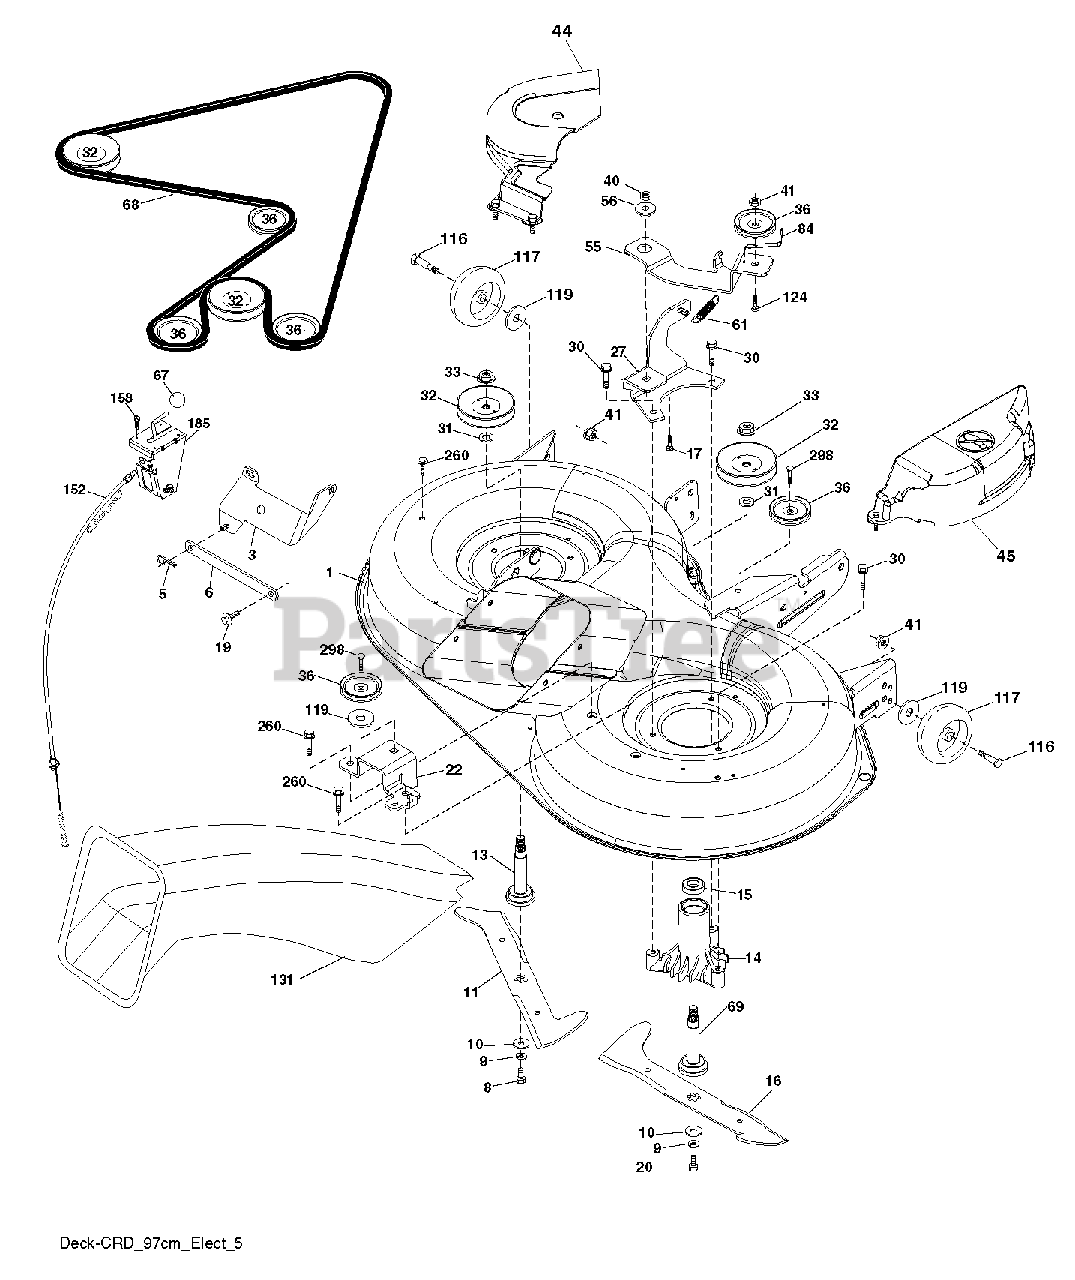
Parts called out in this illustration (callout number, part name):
1	DECK.WLDT.97.CRD.2GWB
3	BRACKET.ASM.BAR.SWAY.CHASS
5	RETAINER-SPRNG RB
6	BAR SWAY
8	Bolt, 3/8-24 X 1.25 Gr8
9	LOCKWASHER
11	BLADE.3N1.LH.CRD.97
13	SHAFT ASM VENT
16	BLADE.3N1.RH.CRD.97
17	BOLT.3/8-14X1.25
19	BOLT SHD 5/16-18
20	BOLT.3/8-24X1.25GR8. LHTHRD
22	BRACKET.SUPT.IDLER.REAR.RH
27	BRACKET.ASM.SUSP.REAR.RH.
30	SCREW, WASHER HEAD
31	WASHER.SPACER.MANDREL
32	PULLEY MANDREL
33	NUT.FLANGE.LOCK.TOP
36	PULLEY.IDLER.4.25
40	LOCKNUT
41	NUT LOCK FLG 3/8-16 UNC
56	SPACER.RETAINER.MOWER
67	KNOB T (3/8 HOLE)
68	BELT.DRIVE.CRD.97.2010
69	SHAFT.ASM.W/LWR.BRG.RH.THREAD
84	KEEPER, BELT IDLER
116	BOLT.SHOULDER.3/8-16X3-5/8
117	WHEEL. GUAGE RALLY
124	BOLT.3/8-16X1.50
158	SCREW
185	HEAD ASM. CABLE CLUTCH
260	SCREW 3/8-16X1/2
298	SCREW LT
